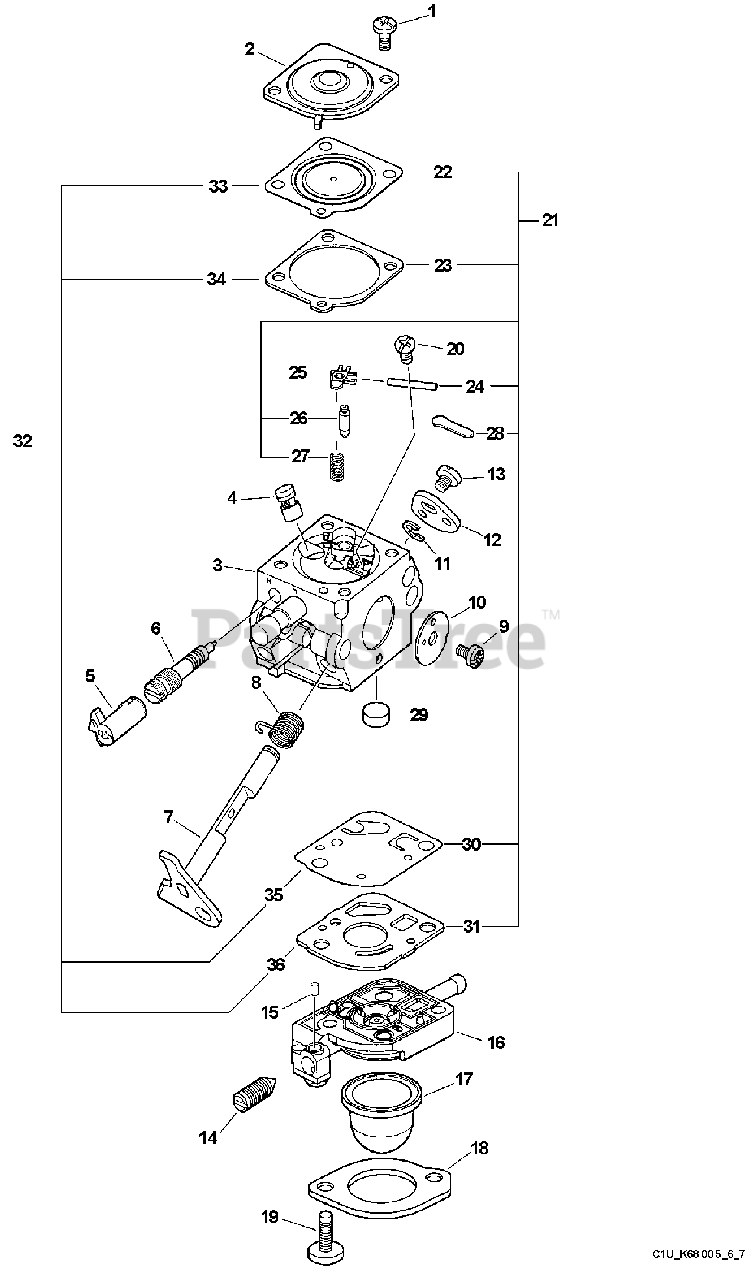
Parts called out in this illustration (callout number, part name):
2	COVER, METERING
3	BODY, CARBURETOR
4	NOZZLE, CHECK VALVE
5	CAP, LIMITER
6	NEEDLE - HIGH SPEED
7	SHAFT, THROTTLE
8	SPRING, TRIGGER
10	VALVE, THROTTLE
11	RING, RETAINING
12	LEVER, THROTTLE
14	SCREW, IDLE ADJUST
15	PIECE, FRICTION
16	BASE, PURGE
17	BULB, PURGE
18	RETAINER, PURGE BULB
19	SCREW, RETAINER
20	SCREW, METERING LEVER PIN
21	REPAIR KIT
22	DIAPHRAGM, METERING
23	GASKET, DIAPHRAGM
24	PIN, METERING LEVER
25	LEVER, METERING
26	VALVE, INLET NEEDLE
27	SPRING, METERING LEVER
28	PLUG, WELCH
29	STRAINER
30	DIAPHRAGM, PUMP
31	GASKET, PUMP
32	DIAPHRAGM/GASKET KIT
33	DIAPHRAGM, METERING
34	GASKET, DIAPHRAGM
35	DIAPHRAGM, PUMP
36	GASKET, PUMP
